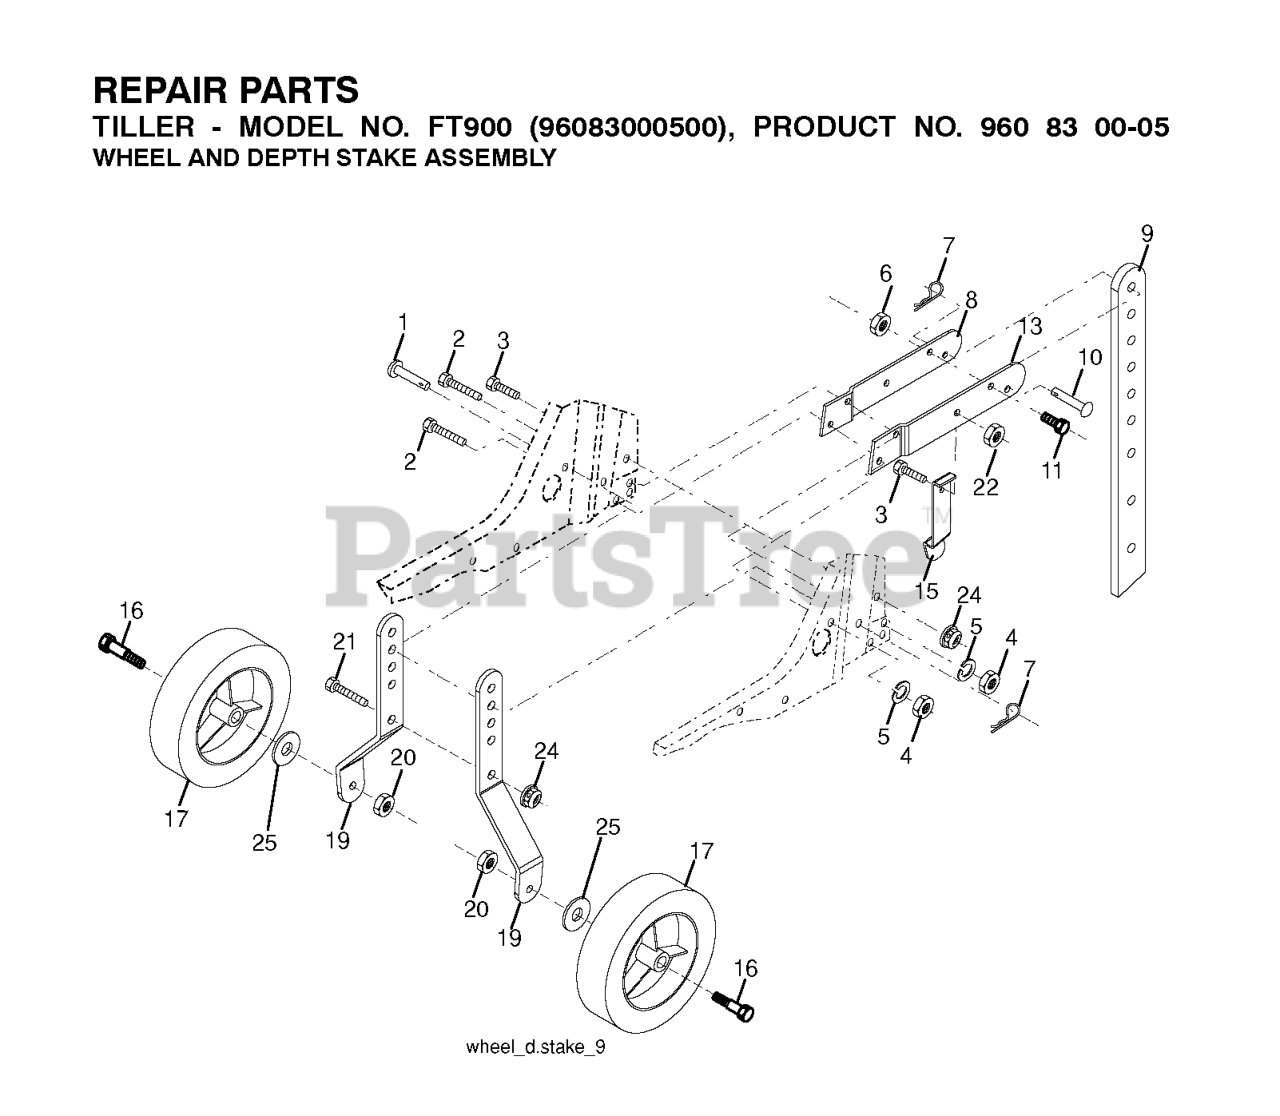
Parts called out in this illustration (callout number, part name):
1	PIN
2	BOLT
3	BOLT
5	WASHER.LOCK.HVY.HLCL.SPR.5/16
6	NUT
7	SPRING TI
8	SUPPORT.STAKE.RH.BLK(2 2MC)
9	RP STAKE.DEPTH.13.25.W/9HOLES
10	REPL BY 532 00 49-29
11	BOLT
13	REPL BY 532 14 92-09
15	REPL BY 532 12 47-24
16	BOLT.SHOULDER
17	WHEEL.8X1.75.STORM.GREY
19	RP.BRACKET.WHEEL.BLACK
21	BOLT RB
22	NUT.71038.31-18.HEX.NYLOCK
24	LOCKNUT-FLANGE 5/16-18
25	Washer 1 17/32 X 7/8 X 16 Ga
